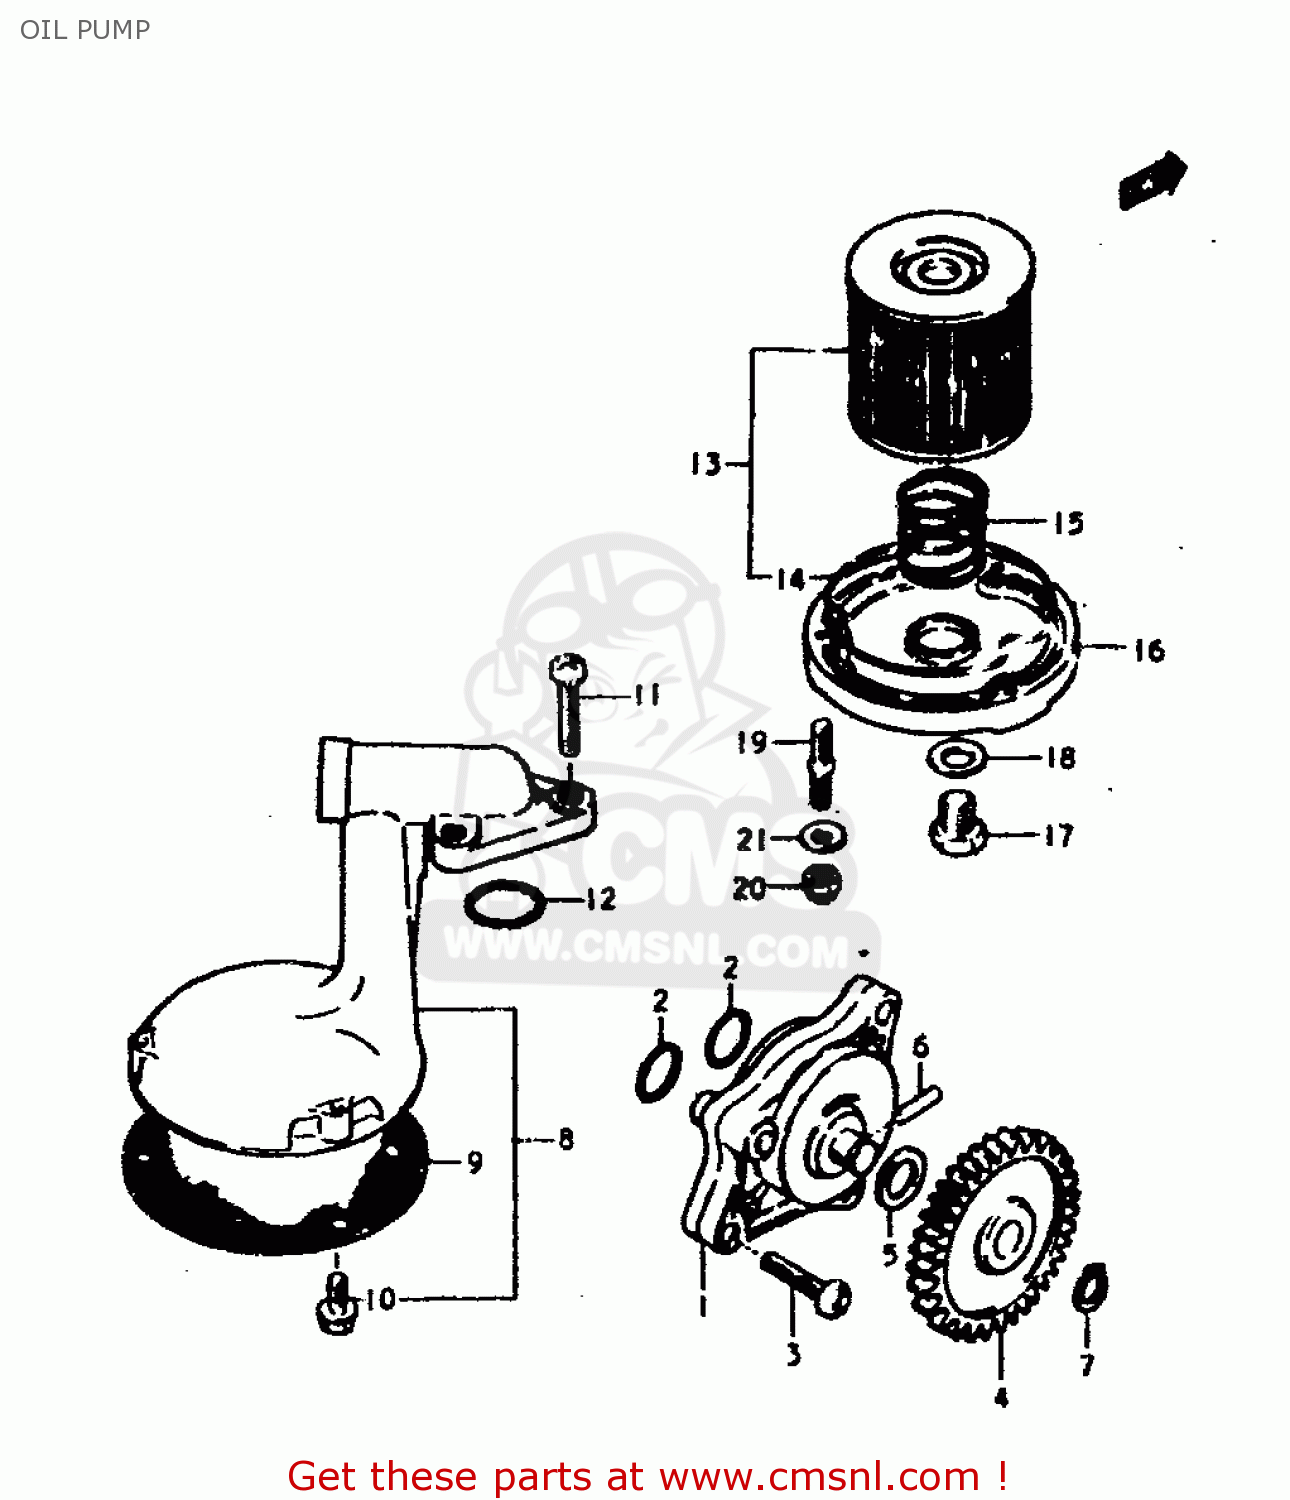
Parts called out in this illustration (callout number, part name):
1	PUMP ASSEMBLY,OIL
2	O RING(D:1.9,ID:13)
3	SCREW
4	GEAR,OIL PUMP DRIVEN
5	SHIM
6	PIN(4X15.8)
7	CIRCLIP
8	STRAINER,ENGINE OIL
9	NET
10	BOLT
11	SCREW
12	O RING(D:2.4,ID:15.8)
13	ENGINE OIL FILTER SET
14	O RING,OIL FILTER CHAMBER CAP
15	SPRING
16	CAP,OIL FILTER
19	STUD 6X20
20	NUT
21	WASHER
